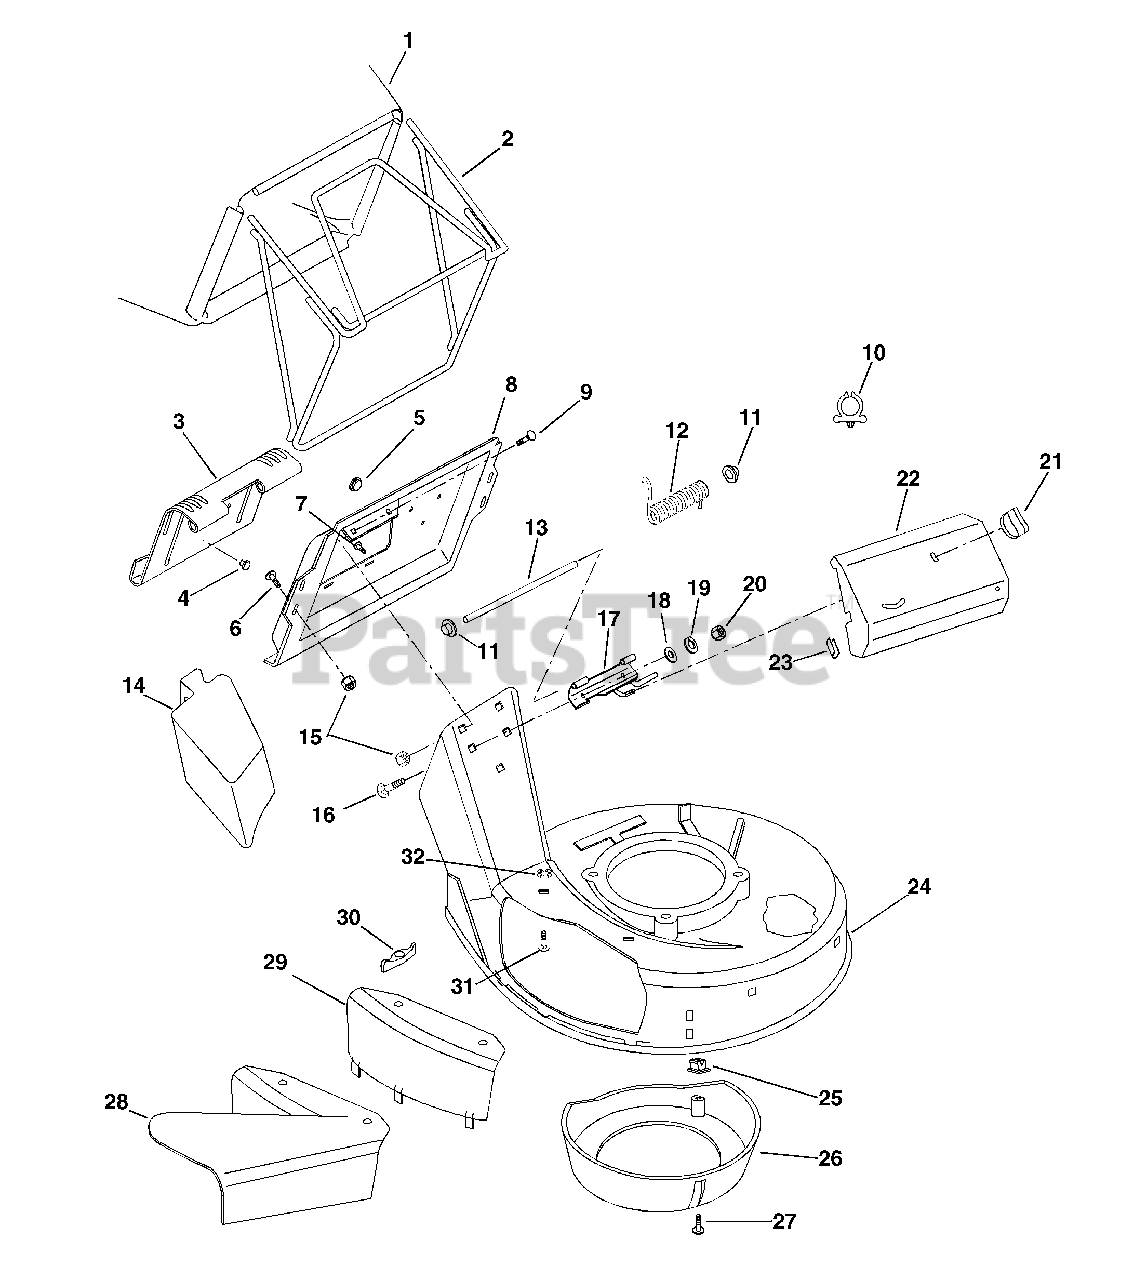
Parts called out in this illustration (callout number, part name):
1	BAG, CONSUMER BLACK 15 OZ/YD2
2	FRAME, BAGGER
3	CATCHER PLATE DOOR
4	BUTTON BUMPER
6	@SCR-TAP 12-24X.50 HWH TR YWZC
7	SCR-TAP 10-24X.375 TORX PHD YZ
8	CATCHER PLATE
9	@BLT-RHDSSQNK .25-20X.38 G2YZ
10	SNAP-IN CLIP
11	PUSH NUT, .25
12	SG-TORS .120X.68X3.09
13	DOOR PIN
14	MULCH MASTER MULCHER ACCESSORY
15	@NUT-SPNLK-FLG .25-20 YWZC
16	@BLT-RDHDSQNK .25-20X.75 G5YZ
17	HINGE BASE WELDMENT
18	WSHR-FL-STL .328X.87X.179 YWZC
19	WSHR-LK .250X.077 HVY YWZC
20	@NUT-HEX .25-20 YWZC
21	WING - NUT
22	COVER, DRIVE
23	TRIM BUMPER
24	MOWER PAN W/SFTY DCLS SCOTTS
25	PLASTIC GROMMET
26	CENTER BAFFLE
27	SCR-TAP 10-16X.62 SLPH AB YWZC
28	SIDE DISCHARGE ASSEMBLY
29	COVER, SIDE DISCHARGE
30	KNOB - WING .312-18 UNC
31	BLT-RDHDSQSHK.31-18X.75 GR2 YW
32	NUT-PUSH .312
